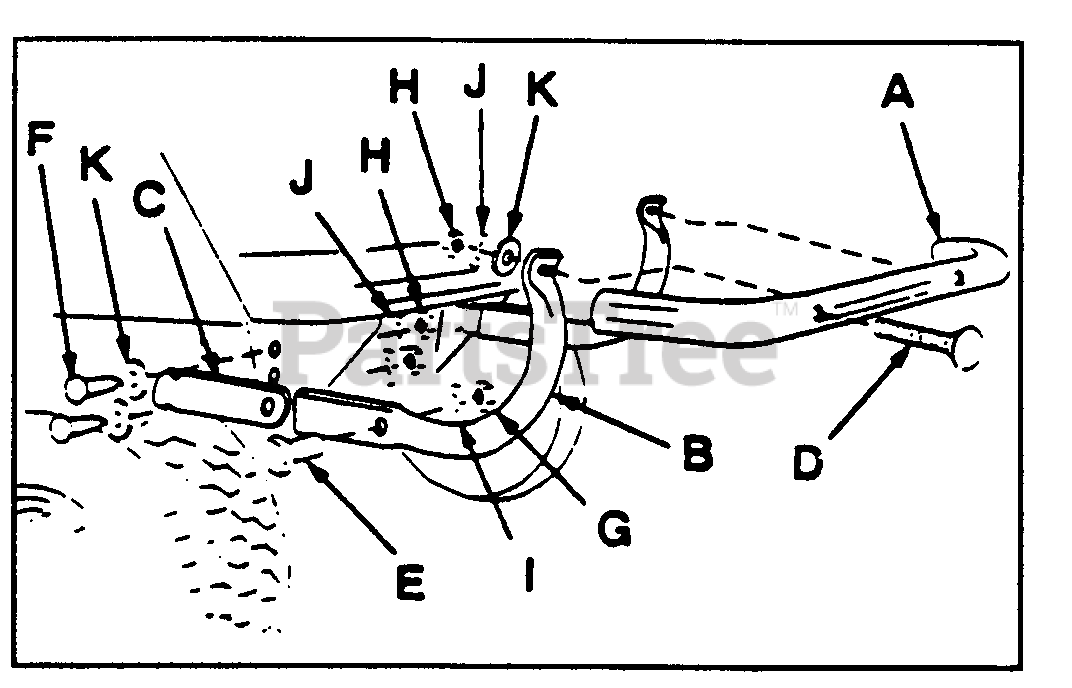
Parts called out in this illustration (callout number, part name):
A	Bumper Tube
B	Bumper Leg
C	Bumper Mount Bracket
D	Carriage Bolt 5/16" x 2" Lg.
E	Hex Bolt 3/8-16 x 1" Lg.
F	Tap Bolt 5/16-18 x 1" Lg.
G	Hex Nut 3/8-16 Thd.
H	Hex Nut 5/16-18 Thd.
I	Lock Washer 3/8"
J	Lock Washer 5/16"
K	Washer, 5/16" Std.
